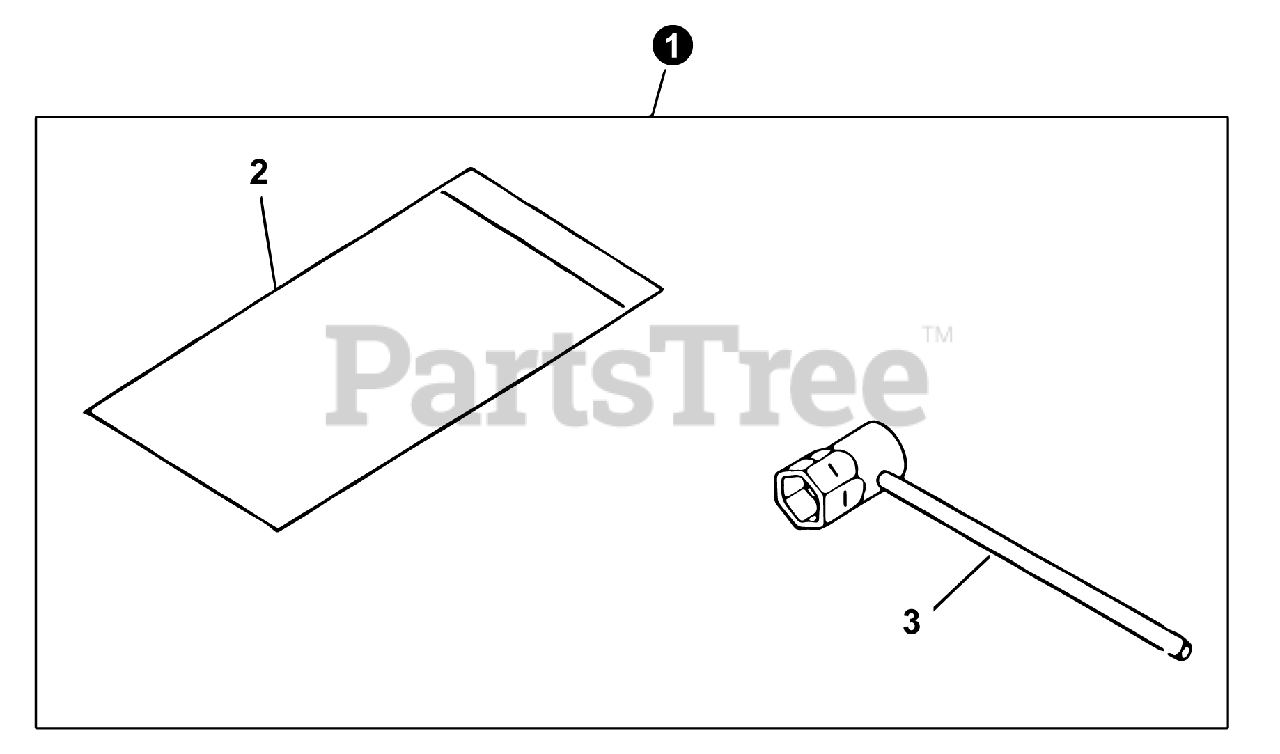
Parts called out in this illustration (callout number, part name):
1	TOOL KIT, SERVICE
2	BAG, TOOL
3	T-WRENCH 19 MM
